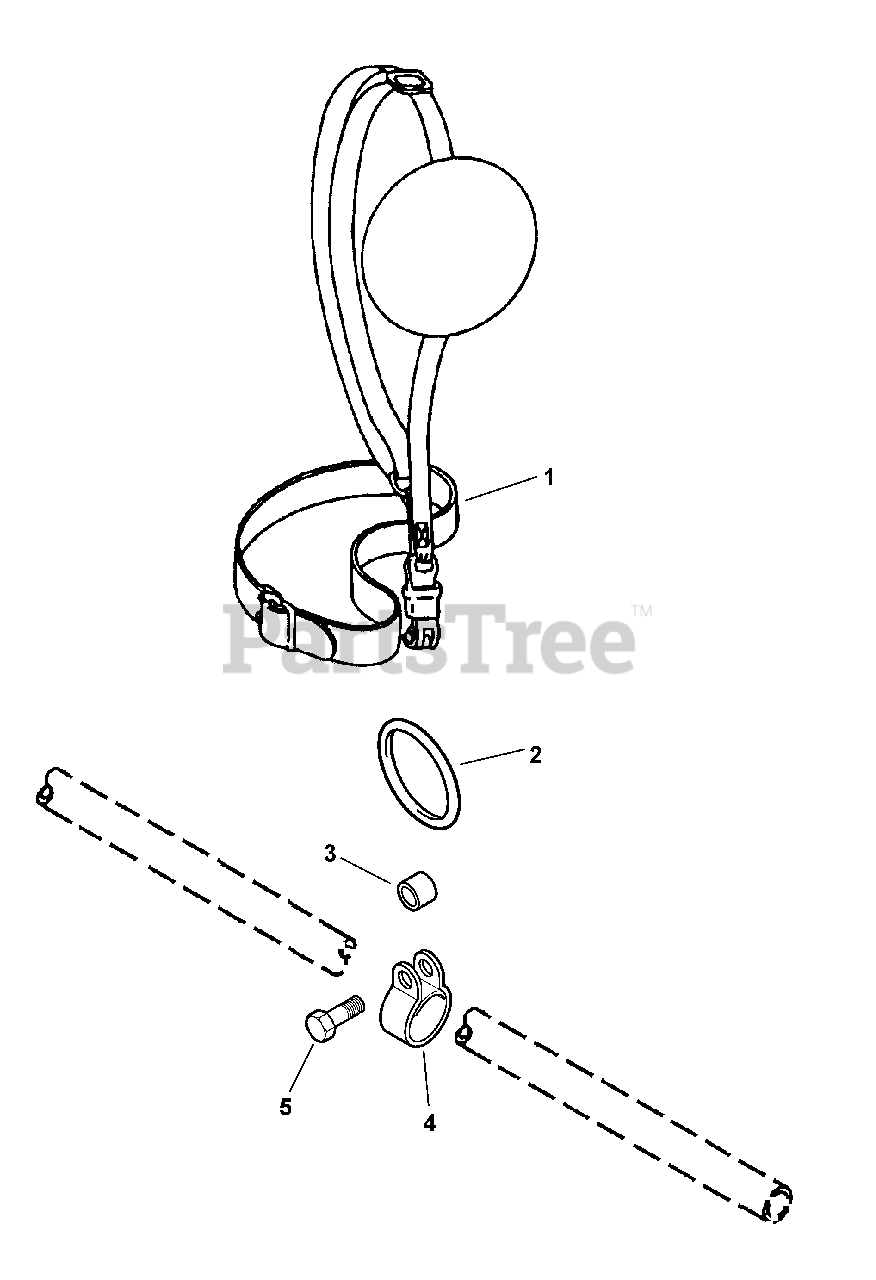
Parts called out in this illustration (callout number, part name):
1	SHOULDER STRAP ASSY
2	HOOK
3	SPACER, GUARD
5	BOLT 5×18
